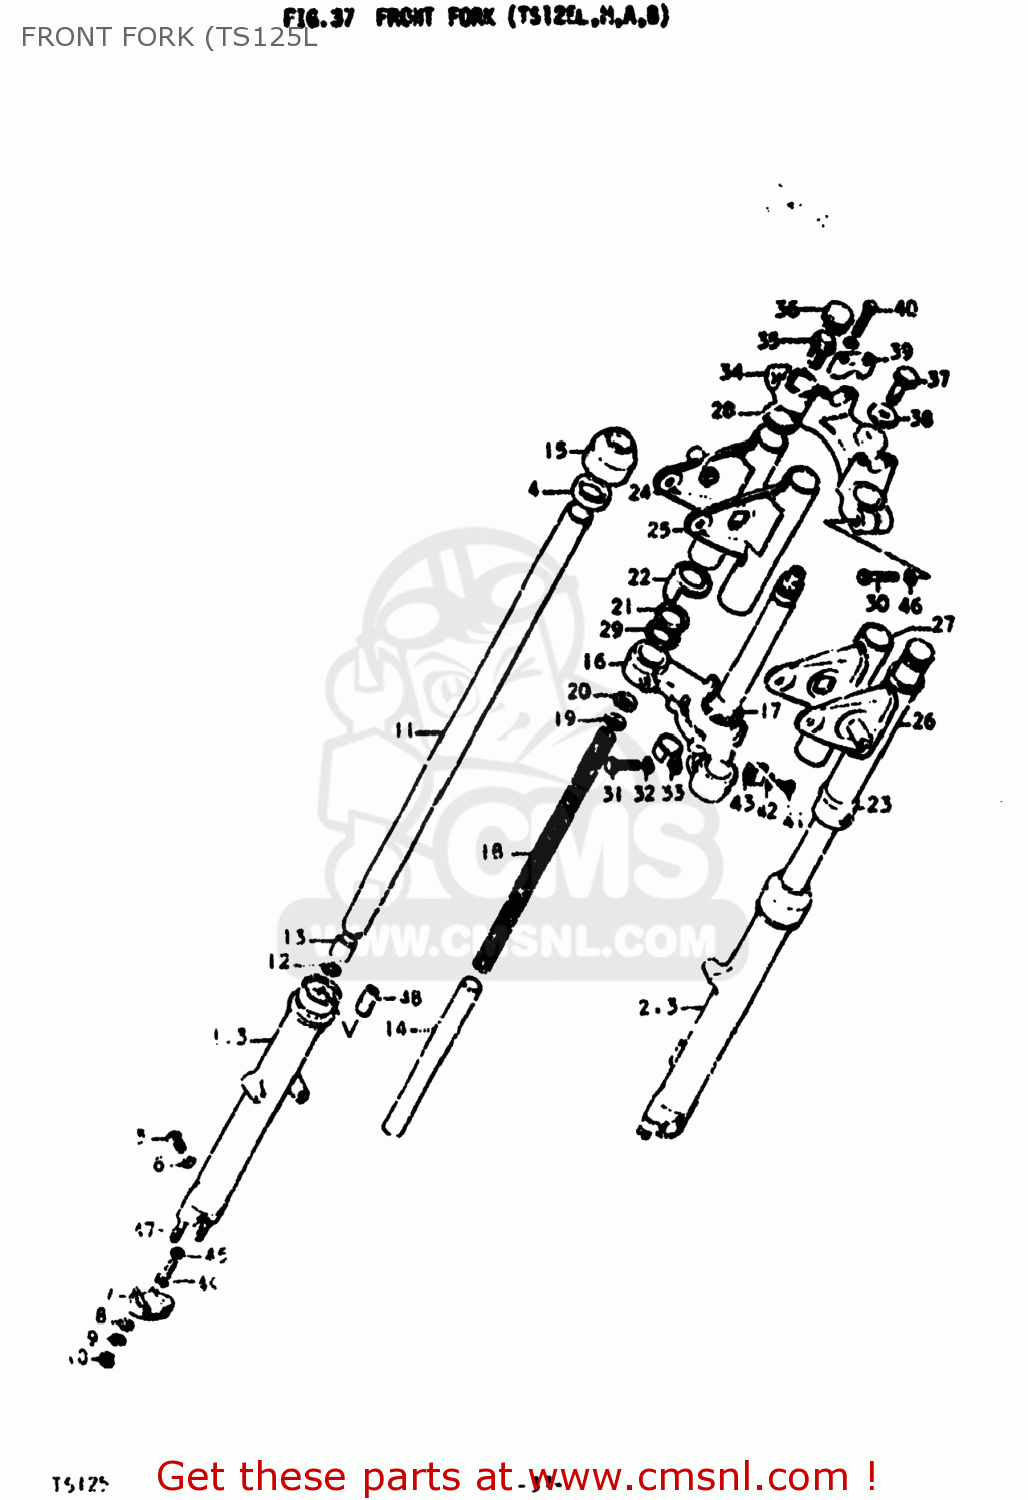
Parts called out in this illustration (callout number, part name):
0	DAMPER SET
1	TUBE,OUTER,RIGHT
2	TUBE,OUTER,LEFT
3	TUBE,OUTER,LEFT
4	SEAL,OIL
5	SCREW
6	GASKET,DRAIN,PLUG (NAS)
7	HOLDER,AXLE
8	WASHER
9	LOCK WASHER
10	NUT (8MM)
11	TUBE,FORK,INNER
12	SNAP RING
13	PISTON
14	CYLINDER,FRONT FORK
15	SEAL,DUST
16	STEM,STEERING
17	RACE,STEERING OUTER LWR
18	SPRING,FRONT FORK
19	GUIDE,SPRING
20	SEAT,SPRING
21	CUSHION,HEADLAMP BRACKET
22	CUSHION,HEADLAMP BRACKET
24	BRACKET,HEADLAMP HOUSING
25	BRACKET,HEADLAMP HOUSING
26	BRACKET,HEADLAMP,LEFT
27	BRACKET,HEADLAMP,LEFT
28	SEAT,HEADLAMP BRACKET
29	GUIDE, COVER
30	BOLT,FORK INNER TUBE F
31	BOLT,FR FORK LWR(12X33)
32	WASHER,LOCK 12
33	CLIP
34	HEAD,STEERING STEM
35	CAP
36	CAP,FRONT FORK
37	BOLT,FORK INNER TUBE
38	WASHER
39	HOLDER,HANDLEBAR
40	Bolt
41	SCREW
42	LOCK WASHER
43	CLIP
44	BOLT
45	GASKET
46	LOCK WASHER
47	BOLT,STUD
48	PIECE,OIL LOCK
